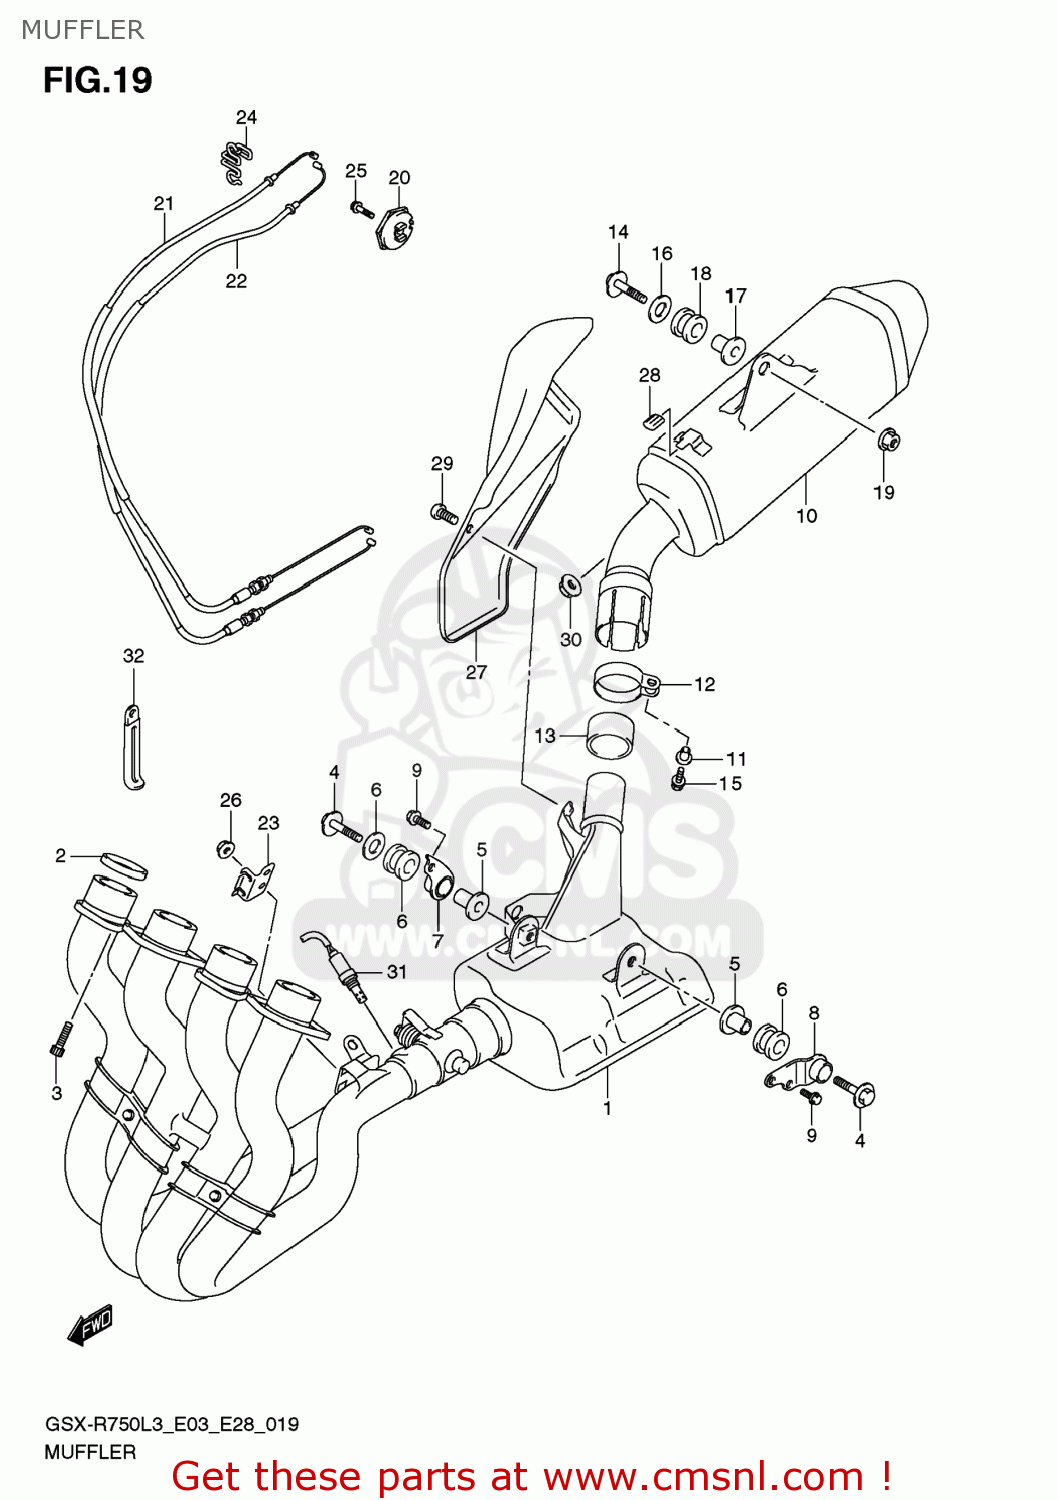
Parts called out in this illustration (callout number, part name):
1	EXHAUST
2	GASKET,EXHAUST PIPE
3	BOLT(8X25)
4	BOLT(8X45)
5	SPACER(8.6X12X24.2)
6	CUSHION
7	BRACKET,CHAMBER SPRT,R
8	BRACKET,CHAMBER SPRT,L
9	BOLT
10	BODY,MUFFLER
11	SPACER,MUF CLAMP
12	CLAMP,MUFFLER CONNECTOR
13	CONNECTOR,MUFFLER
14	BOLT(8X45)
15	BOLT(8X40)
16	WASHER(8.5X28X1.5)
17	SPACER(8.6X12X24.2)
18	CUSHION
19	NUT
20	PULLEY,CONTROLLER
21	CABLE,EXHAUST VALVE NO.1
22	CABLE,EXHAUST VALVE NO.2
23	BRACKET,EXHAUST VALVE CABLE
24	GUIDE,EXHAUST VALVE CABLE
25	BOLT
26	NUT
27	COVER,MUFFLER FR
28	GROMMET
29	SCREW(6X10)
30	CUSHION
31	SENSOR,OXYGEN
32	CLAMP(L:45)
